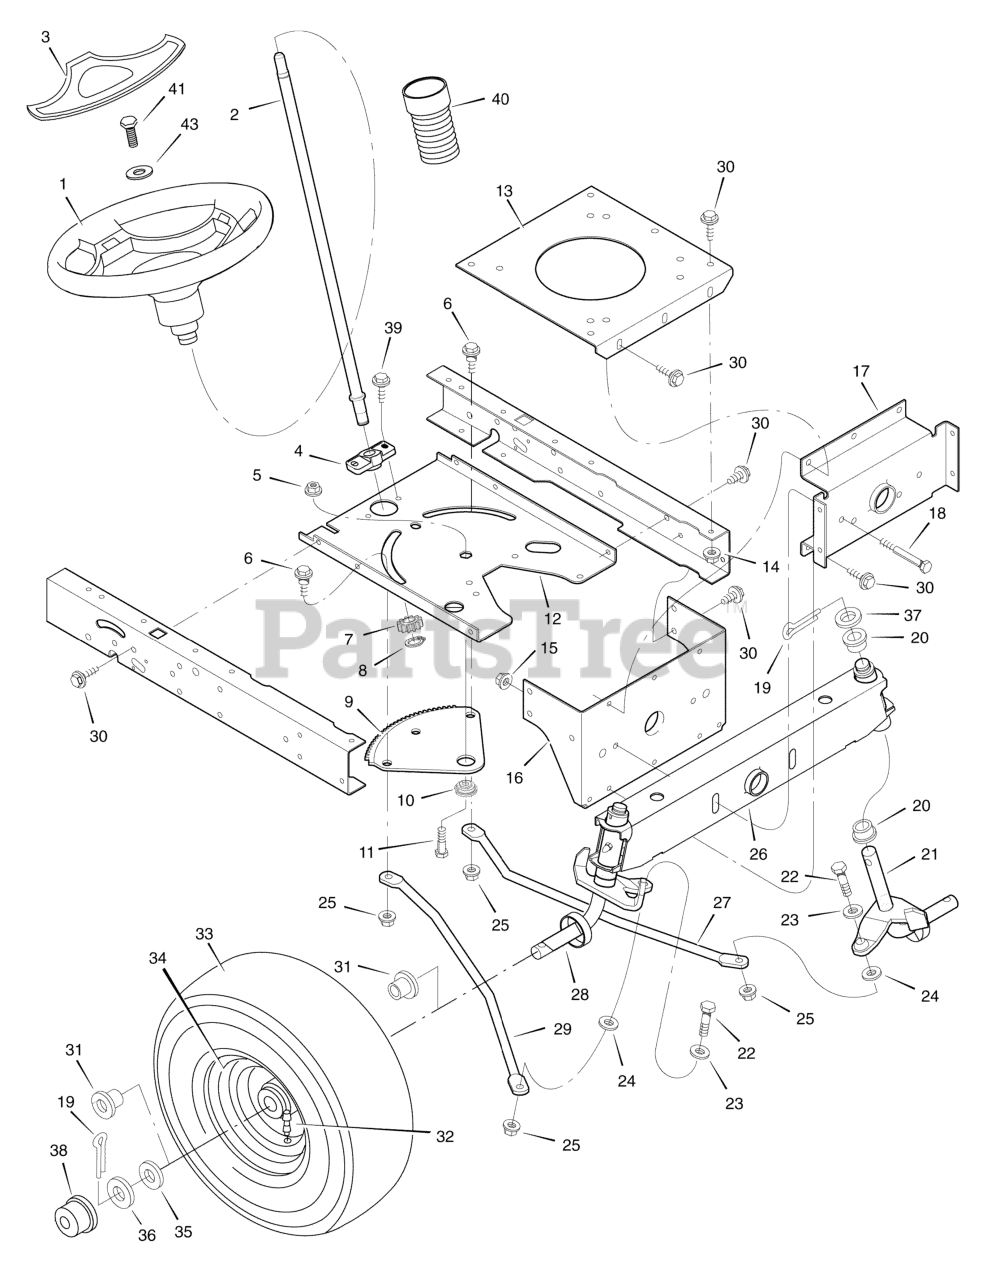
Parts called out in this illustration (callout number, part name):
1	Wheel, Steering
2	Post, Steering
3	Cover, Steering Wheel
4	Bearing
5	Nut, Flange
6	Bolt, Shoulder
7	Gear, Pinion
8	Ring, Snap
9	Gear, Sector
10	Bearing
11	CAPSCREW, Hex Head, 5/16-18 x 1
12	Plate, Steering
13	Plate, Engine
14	Nut, Flange
15	Nut, Flange
16	Bracket, Hanger
17	Axle, Hanger
19	Pin, Cotter
20	Bearing
21	Spindle Assembly, Left
22	Bolt
24	Washer
25	Nut, Flange
26	Axle Assembly
27	Drag Link, Left
28	Spindle Assembly, Right
29	Drag Link, Right
31	Bearing
32	Stem, Valve
34	Wheel and Tire Assembly
38	Hub Cap
40	Bellows
41	Screw, Hex
43	Washer
